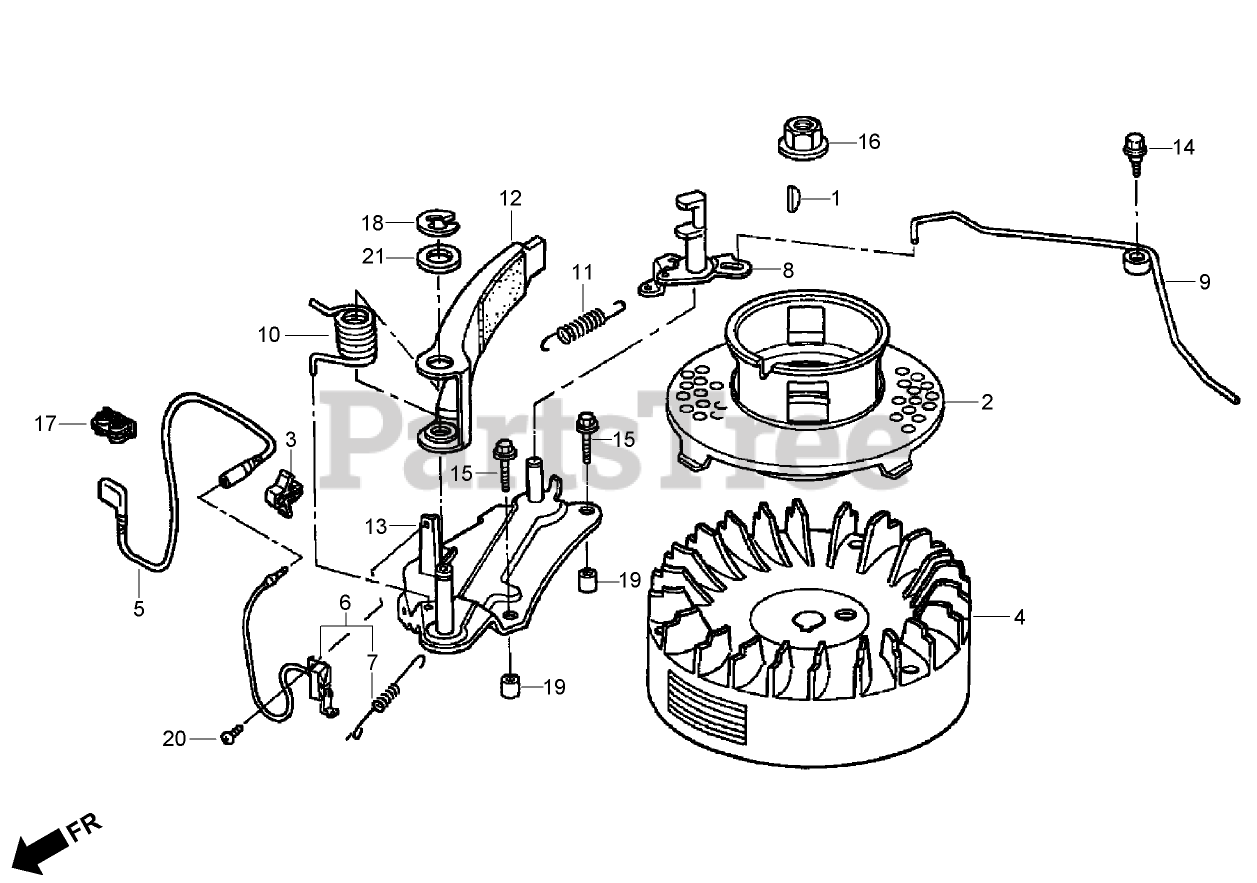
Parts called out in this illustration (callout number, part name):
1	KEY-WOODRUFF, SPECIAL (25X18)
2	PULLEY-STARTER
3	CLIP-WIRE, IGNITION (8 mm)
4	FLYWHEEL (BRAKE)
5	WIRE-SWITCH, STOP (BRAKE)
6	ENGINE STOP SWITCH ASM (BRAKE)
7	SPRING-CONTROL, SWITCH
8	CAM-BRAKE
9	ROD-RETURN, THROTTLE
10	SPRING-BRAKE
11	SPRING-RETURN, BRAKE
12	BRAKE
13	BASE-BRAKE
14	BOLT-FLANGE (6 mm)
15	BOLT-FLANGE (6X23) (C T200)
16	NUT-SPECIAL (14 mm)
17	CLAMP-PIPE
18	E-RING (10 mm)
19	PIN-DOWEL (8X9)
20	Screw-Pan (4X8)
21	WASHER-FLAT (12 mm)
